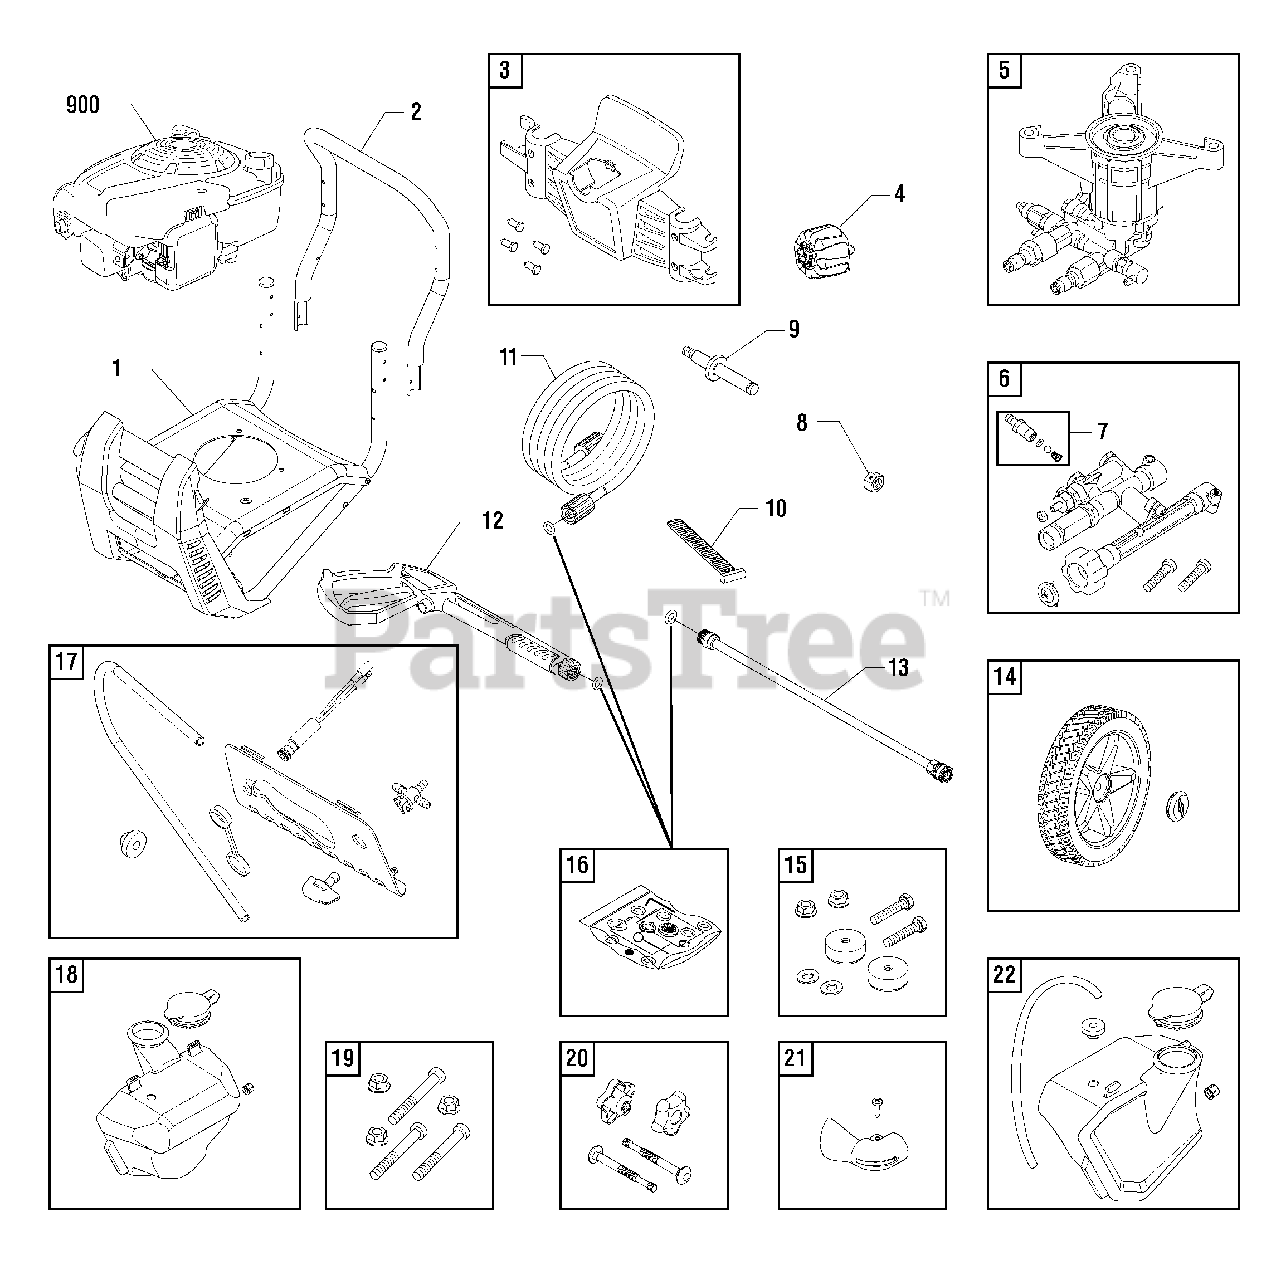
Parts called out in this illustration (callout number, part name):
5	PUMP
12	GUN
15	MOUNT-VIBRATION
17	PANEL-FRONT ASSY
18	TANK-CHEMICAL, LH
19	KIT-HARDWARE PUMP MOUNTING
20	KIT-HARDWARE HANDLE
21	DEFLECTOR-EXHAUST
22	TANK-CHEMICAL, RH
900	** ENGINE
